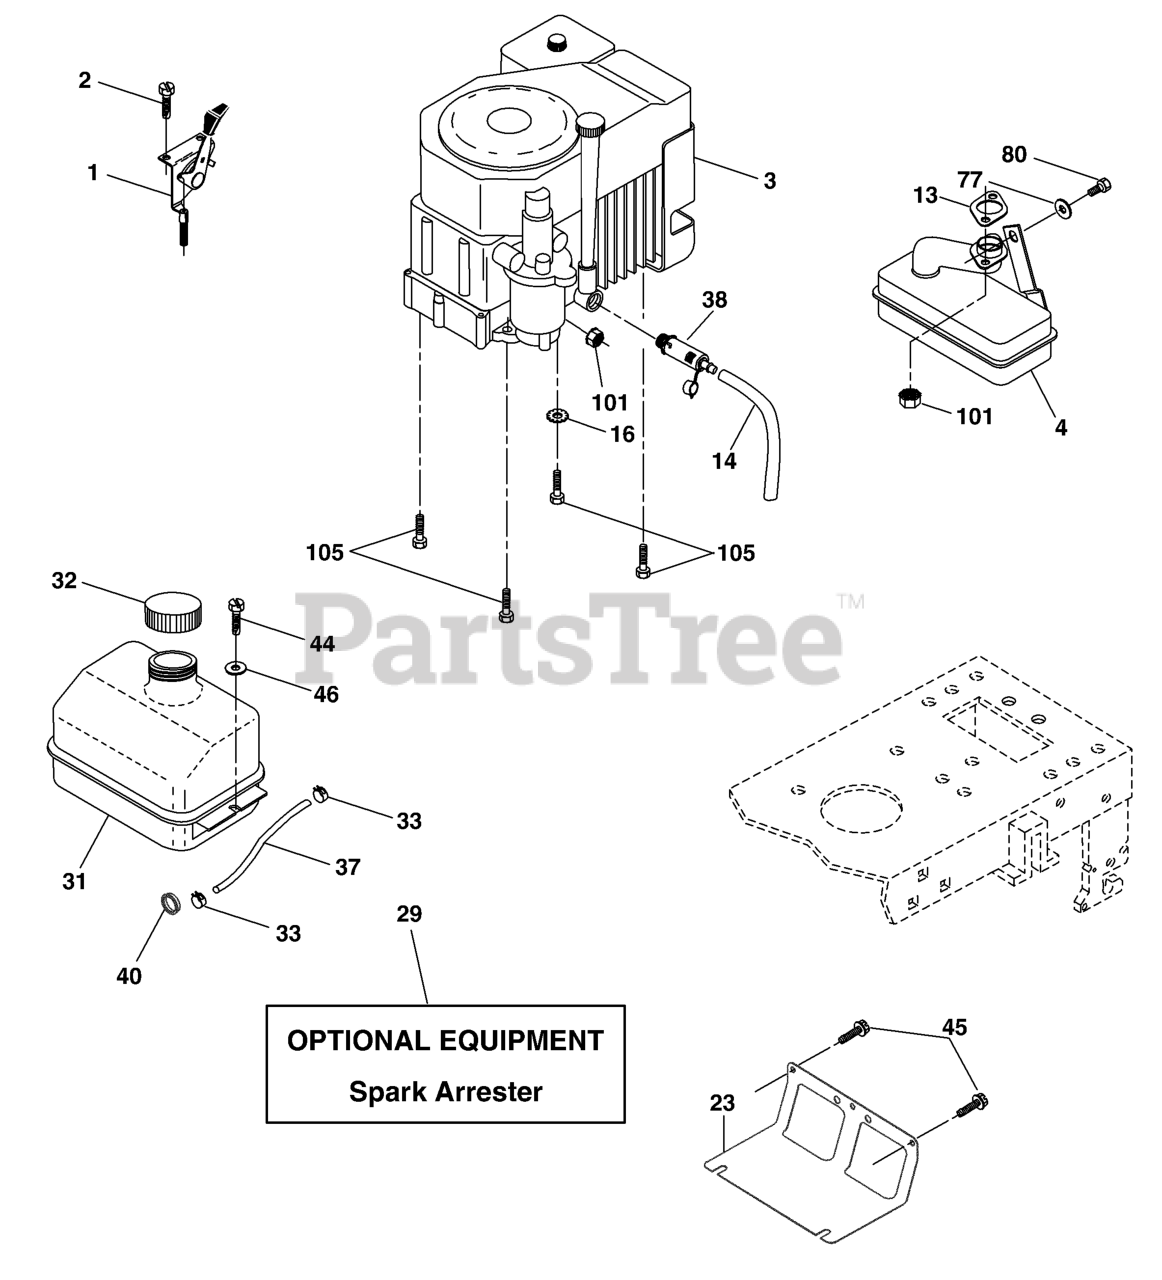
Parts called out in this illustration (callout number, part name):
1	CONTROL.THROTTLE.LT/YT
2	SCREW
4	MUFFLER.KOHL.CV491.W/PORT
13	KOHLER GASKET
14	TUBE, DRAIN OIL ASM.
16	LOCKWASHER
23	SHIELD.BROWNING.DBR.GUARD
29	KIT.SPARK ARRESTOR 794945 B&S
31	TANK.ASM.FUEL.FRONT.W/CAP
32	FUEL CAP
33	HOSE CLAMP
37	LINE.FUEL.20
38	PLUG DRAIN OIL EASY
40	BUSHING.SNAP.NYL.BLK.
44	SCREW HEXWSHR 1/4-20X3/4
45	SCREW, 3/8-16X3/4
46	WASHER
77	WASHER
80	Bolt Hex Hd 5/16-18unc x 1/2
101	FLANGE NUT
105	SCREW 3/8-16X1
